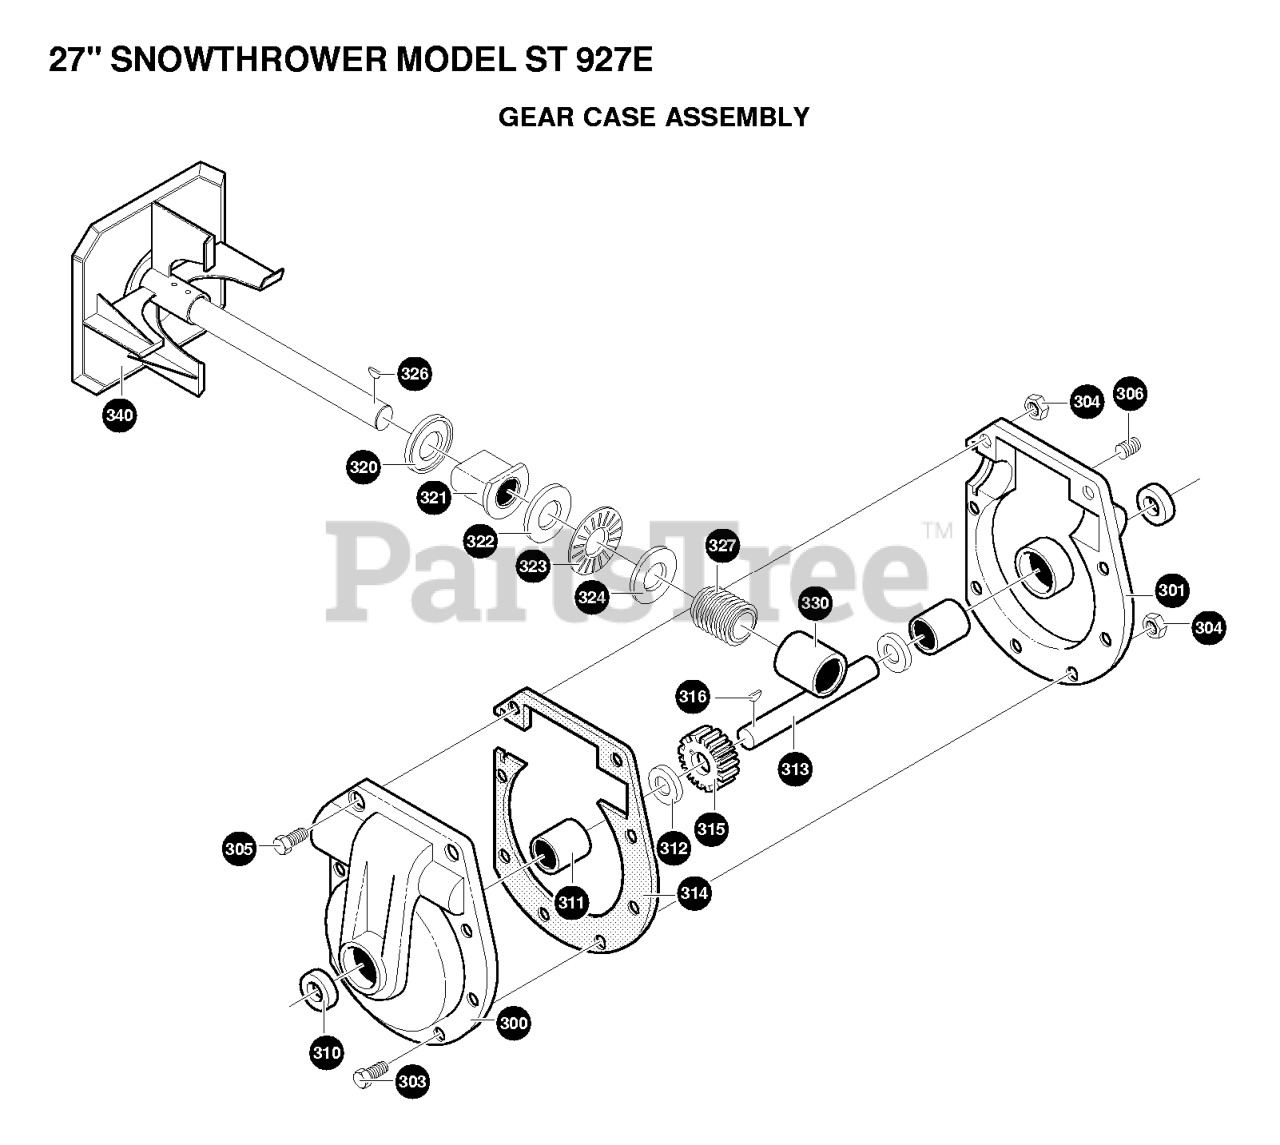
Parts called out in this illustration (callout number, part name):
300	GEAR CASE, RH
301	GEAR CASE, LH
304	NUT,5/16-24
305	SCREW, 5/16-24X1.50 HHC
310	OIL SEAL
313	SHAFT, AUGER OUTPUT MF 22"
316	WOODRUFF KEY
321	FLANGE BEARING
323	ROLLER BEARING
326	HI-PRO KEY
340	IMPEL ASSY
